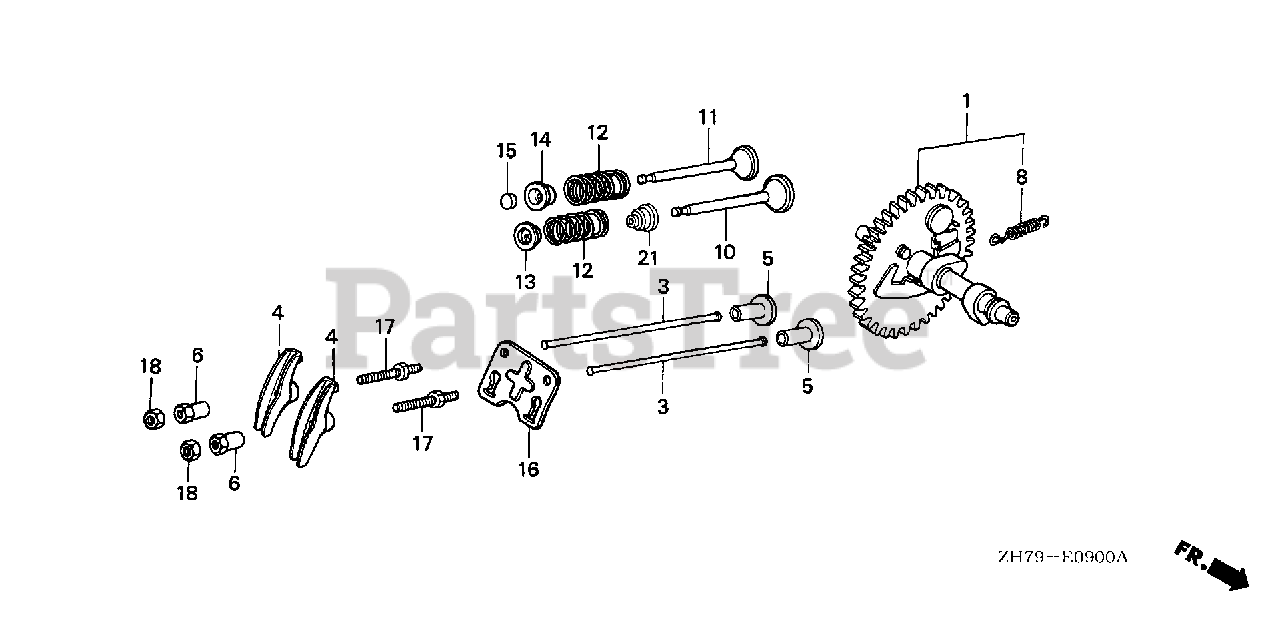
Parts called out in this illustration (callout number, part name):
1	CAMSHAFT ASSY.
3	ROD, PUSH
4	ARM, VALVE ROCKER
5	LIFTER, VALVE
6	PIVOT, ROCKER ARM
8	SPRING, WEIGHT RETURN
10	VALVE, IN.
11	VALVE, EX.
12	SPRING, VALVE
13	RETAINER, IN. VALVE SPRING
14	RETAINER, EX. VALVE SPRING
15	ROTATOR, VALVE
16	PLATE, PUSH ROD GUIDE
17	BOLT, PIVOT (8MM)
18	NUT, PIVOT ADJ.
21	SEAL, VALVE STEM
